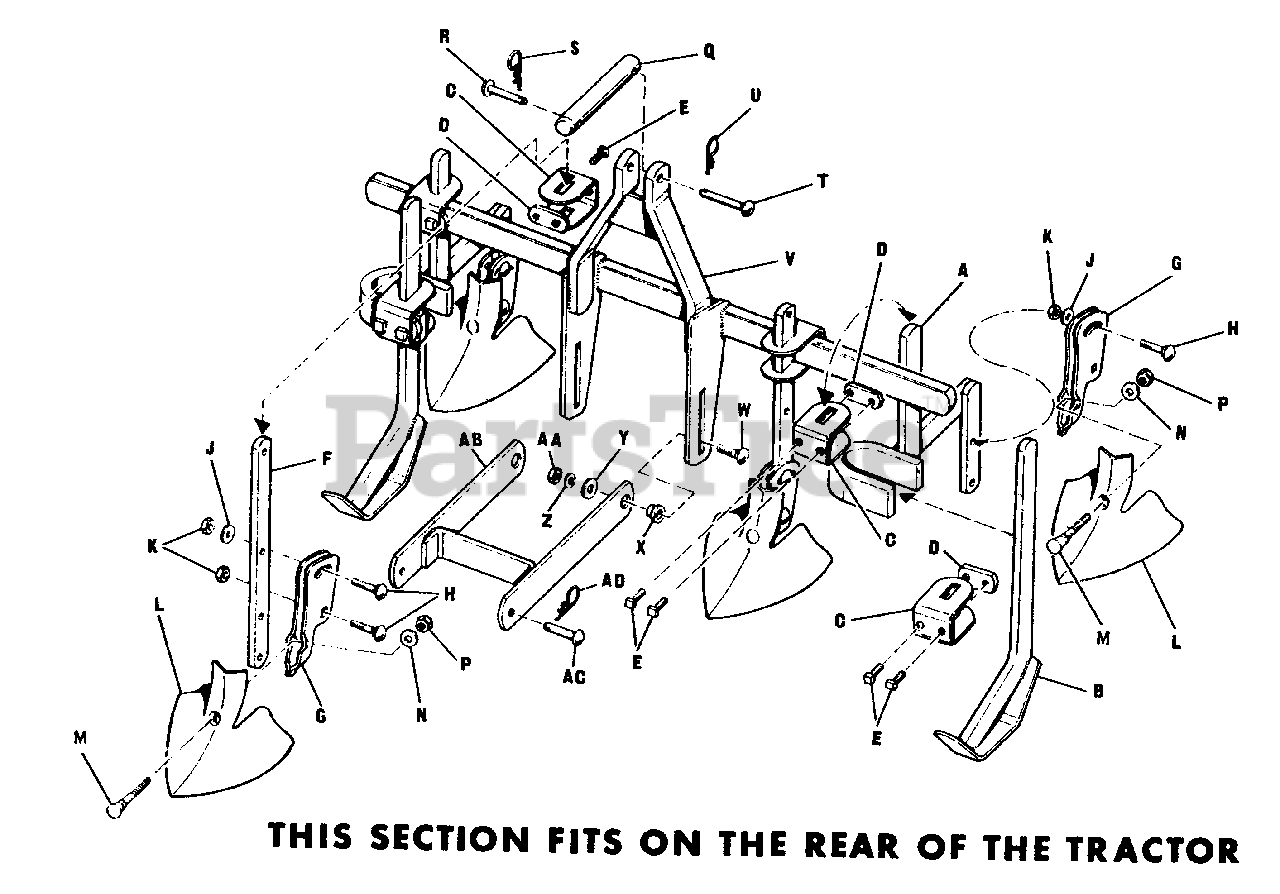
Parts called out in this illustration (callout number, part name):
A	Standard Tool Assembly
B	Shoe Weld Assembly
C	Clamp Shank, 3/16" x 2" x 8"
D	Special Nut, 5/16" x 1" x 2-1/2"
E	Set Screw, 3/8"-16 x 1"
F	Standard Tool, 7/16" x 1-1/4" x 14-1/8"
G	Tool Holder Assembly
H	Carriage Bolt, 3/8"-16 x 1-1/4"
J	Plain Washer, 3/8"
K	Full Hex. Nut, 3/8"-16
L	Universal Sweep 3/16" x 8"
M	Plow Bolt, 7/16"-14 x 2"
N	Plain Washer. 7/16"
P	Full Hex. Nut 7/16"-14
Q	Attaching Rod
R	Pin, 3/8" x 2"
S	Spring Clip
T	Pin, 3/8" x 2-3/8"
U	Spring Clip
V	Rear Tool Bar Assembly
W	Carriage Bolt, 7/16"-14 x 1-1/2"
Y	Washer, 3/8"
Z	Lock Washer, 7/16"
AA	Full Hex. Nut, 7/16"-14
AB	Arm Assembly
AC	Rd. Hd. Pin, 7/l6" x 1-3/4"
AD	Clip Spring
